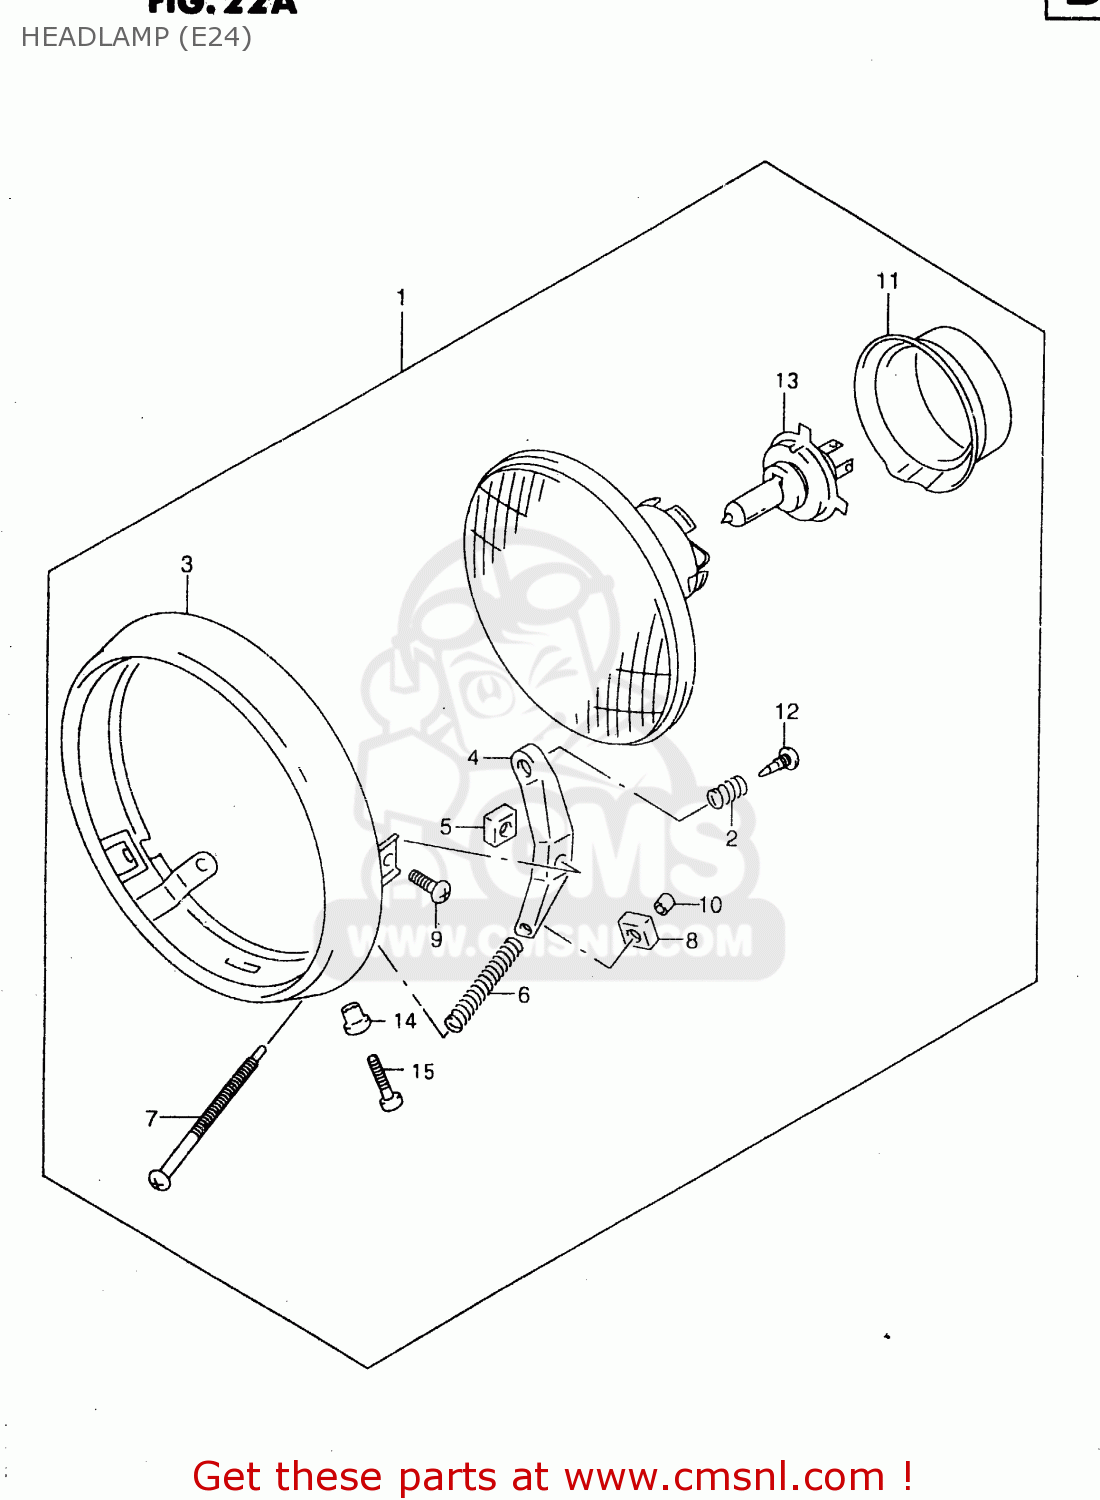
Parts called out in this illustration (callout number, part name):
1	HEADLAMP ASSEMBLY
2	SPRING
3	RIM,HEAD LAMP
4	STAY
5	NUT
6	SPRING
7	ADJUSTER SCREW
8	NUT,HEADLAMP ADJUST
9	SCREW
10	CAP,SCREW
11	COVER,SOCKET
12	SCREW
13	BULB(12V60/55W,H4)
14	SPACER,HEADLAMP
15	SCREW
